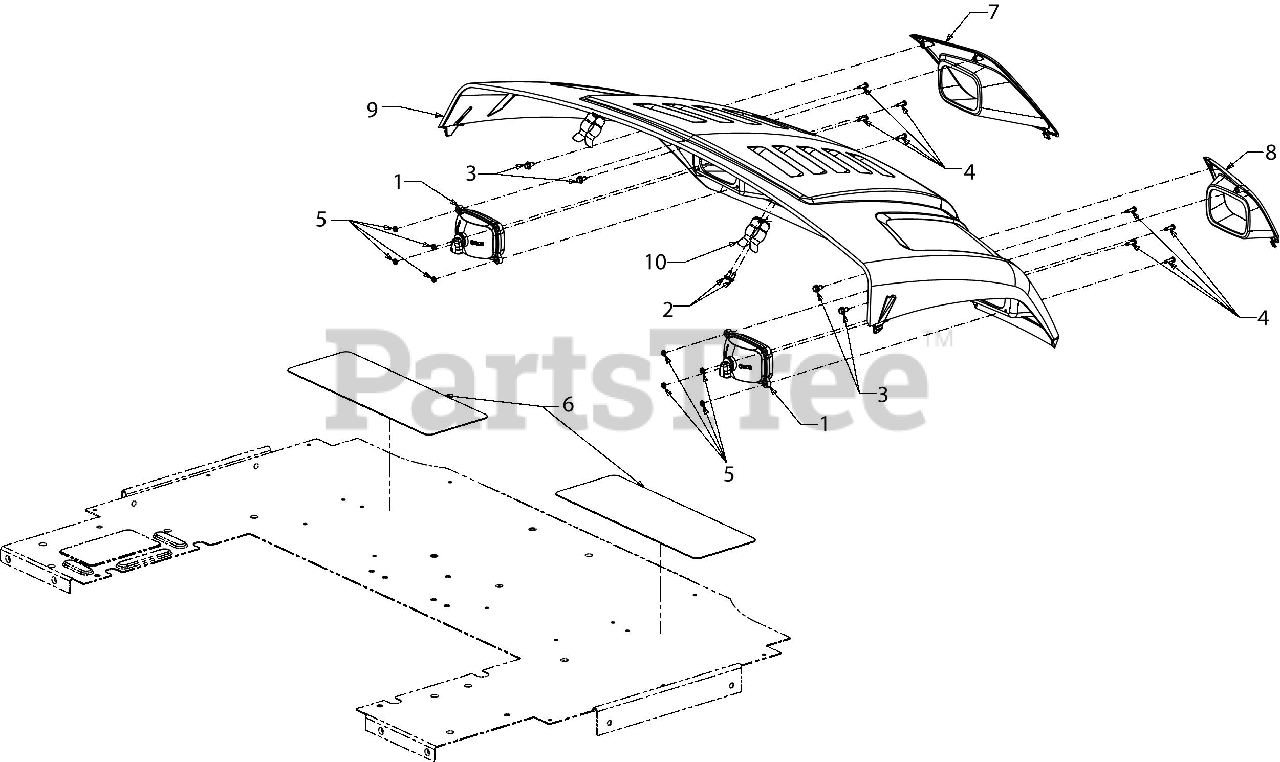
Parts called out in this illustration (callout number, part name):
1	HEADLIGHT ASSEMBLY
2	HEX SCREW #12-16 x .50
3	SCREW 1/4-20X.625
4	SCREW #10-24 x .750
5	LOCK NUT 10-24
6	FOOT REST PAD
7	HEADLIGHT BEZEL (LH)
8	HEADLIGHT BEZEL (RH)
9	UV HOOD (MTD RED)
10	HOOD LATCH SPRING
